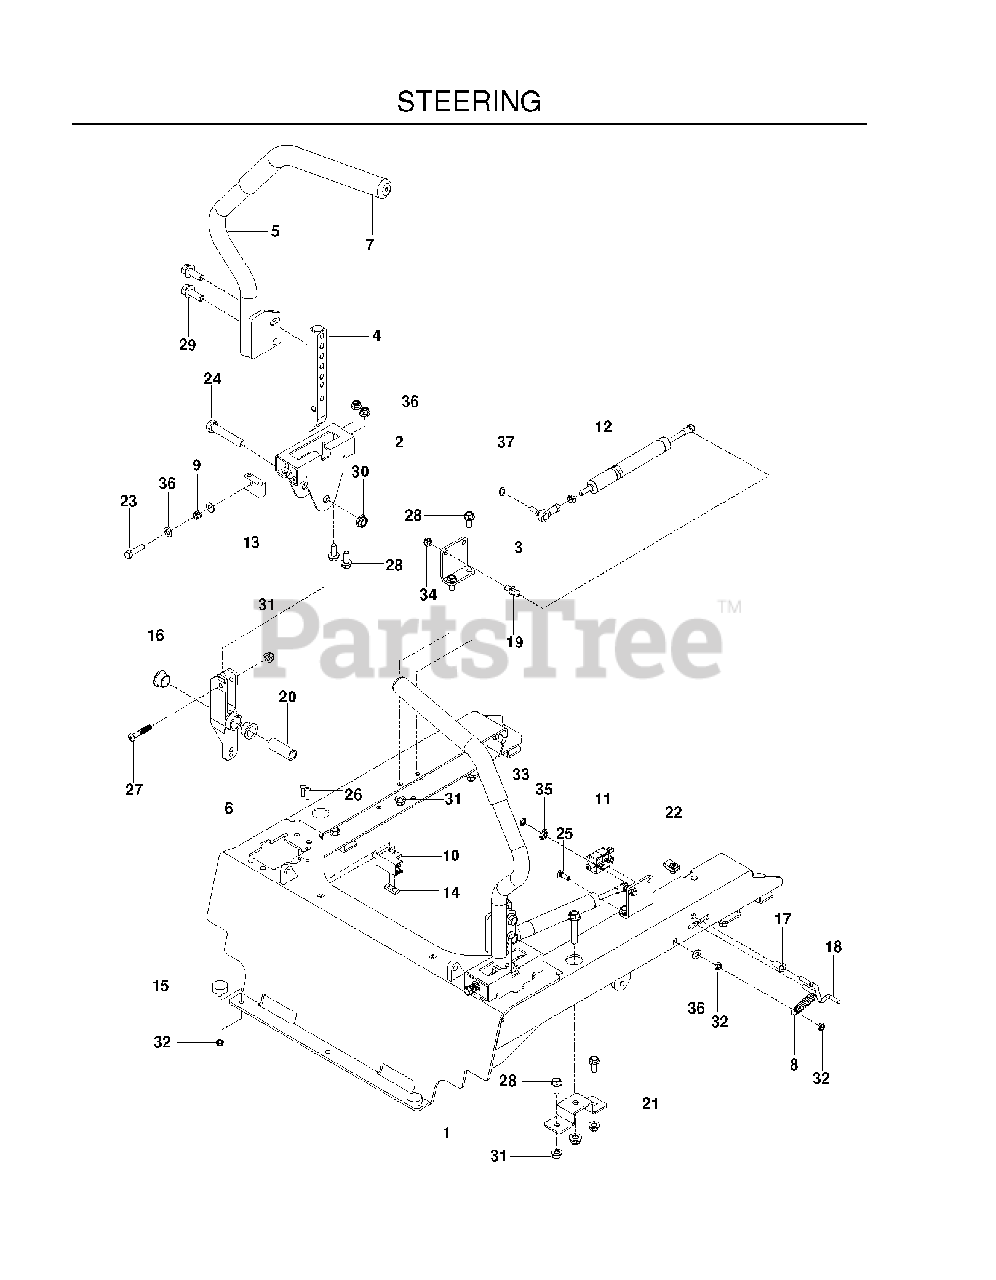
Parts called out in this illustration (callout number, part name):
4	LEVER, MOTION
8	GRIP - DRIVE LEVER
9	SPRING, EXTENSION
12	SWITCH, BRAKE 3P
13	ASSEMBLY, DAMPENER
15	BLOCK, LOWER
16	BUMPER, 1/4-20 STUD, 1/4
17	BEARING, FLANGE
18	BUSHING, 1/4 FLANGE
19	LINK, SWITCH
20	10MM BALL STUD
22	MOUNT, MID-SECTION, BLK
23	U-CLIP 5/16-18 NUT RETAINER
25	HCS 1/2C X 2 3/4
26	RHSNB 1/4C X 3/4
27	SCR #10-24 X .75 SKT HD BLK
29	HHFS 5/16-18 X 3/4
30	HHFS 3/8-16 X 1 GRD 5 ZD
31	NUT 1/2-13 HEX JM NYL
32	5/16-18 NYLOC FLANGE NUT
33	JAM NUT 1/4C
34	NUT PUSH
35	NUT 5/16 NYLOC
36	BOLT RETAINER 3/8
37	FLAT WASHER 5/16 SAE
